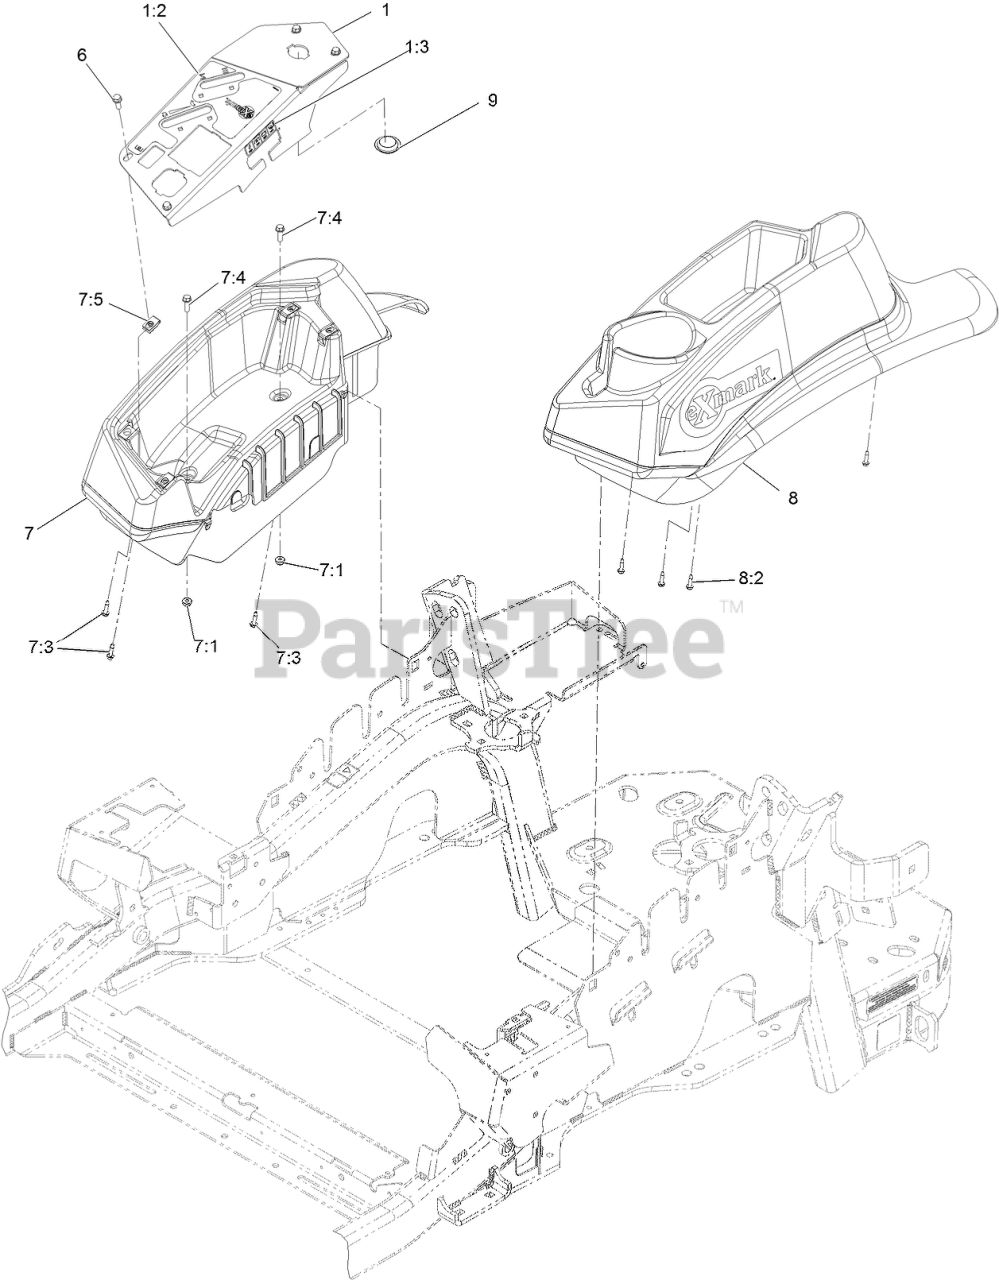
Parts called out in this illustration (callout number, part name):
1	ASM-PANEL, CONTROL W/DECAL
1:2	DECAL-CONTROL PANEL NON-EFI
1:3	DECAL-FUSES
6	SCREW-HWH
7	CONSOLE,RH NARROW ASM
7:3	SCREW,THD FORM,HWH
7:4	SCREW-HWH
8	CONSOLE.LH NARROW ASM
8:2	SCREW,THD FORM,HWH
9	PLUG-PLASTIC
